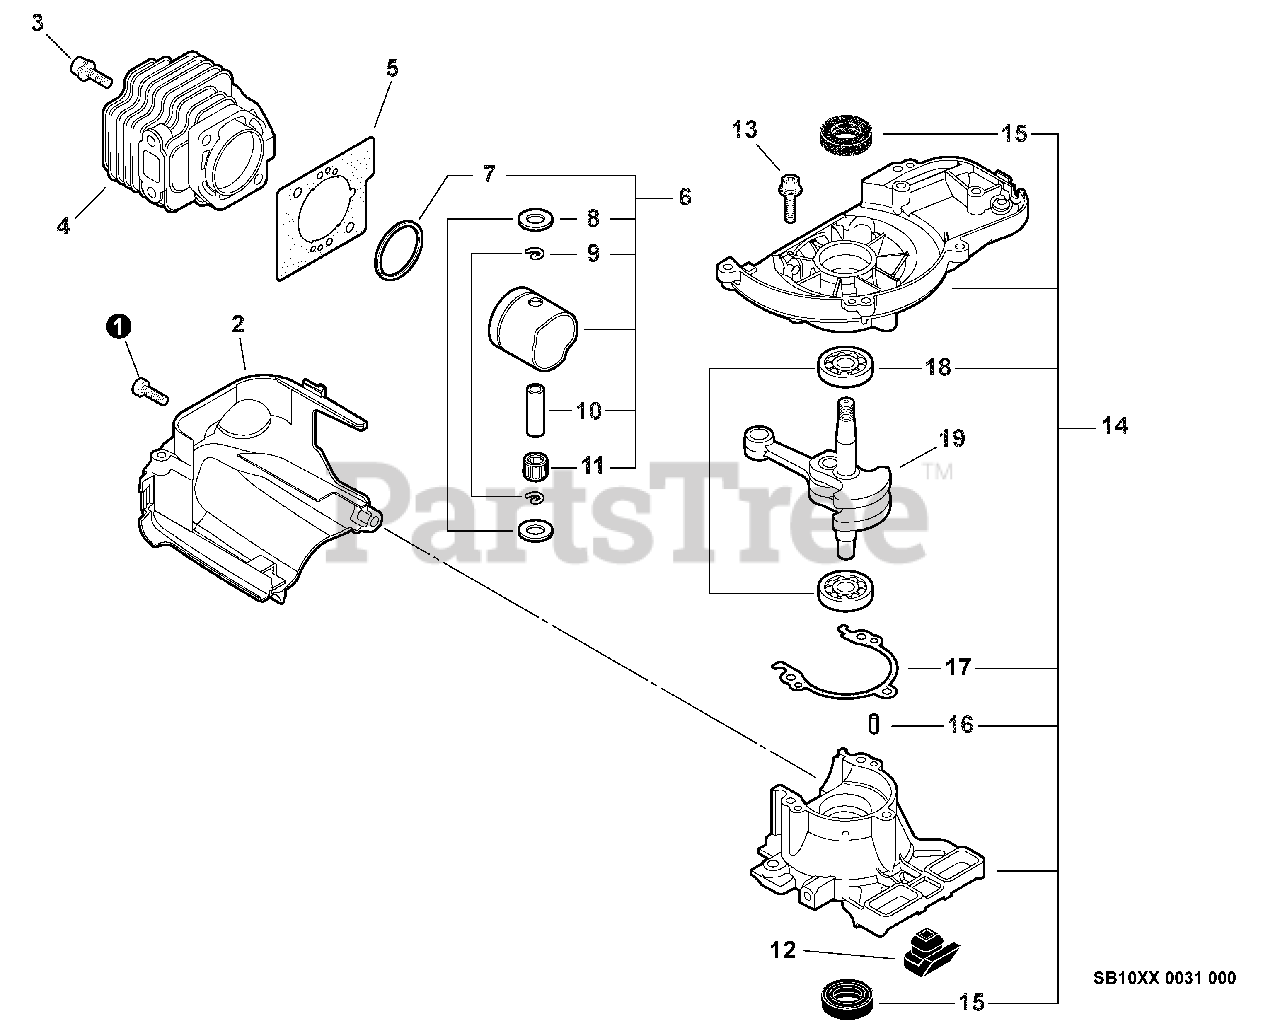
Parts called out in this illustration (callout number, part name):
1	BOLT, TORX 5×16
2	COVER, ENGINE
4	CYLINDER
5	GASKET, CYLINDER
6	PISTON KIT
7	RING, PISTON
8	WASHER, THRUST
9	RING, SNAP
10	PIN, PISTON 8
11	BEARING, NEEDLE
12	CUSHION
13	BOLT 5×28
14	CRANKCASE KIT
15	SEAL, OIL
16	PIN, LOCATING 4×8
17	GASKET, CRANKCASE
18	BEARING, BALL
19	CRANKSHAFT ASSY
